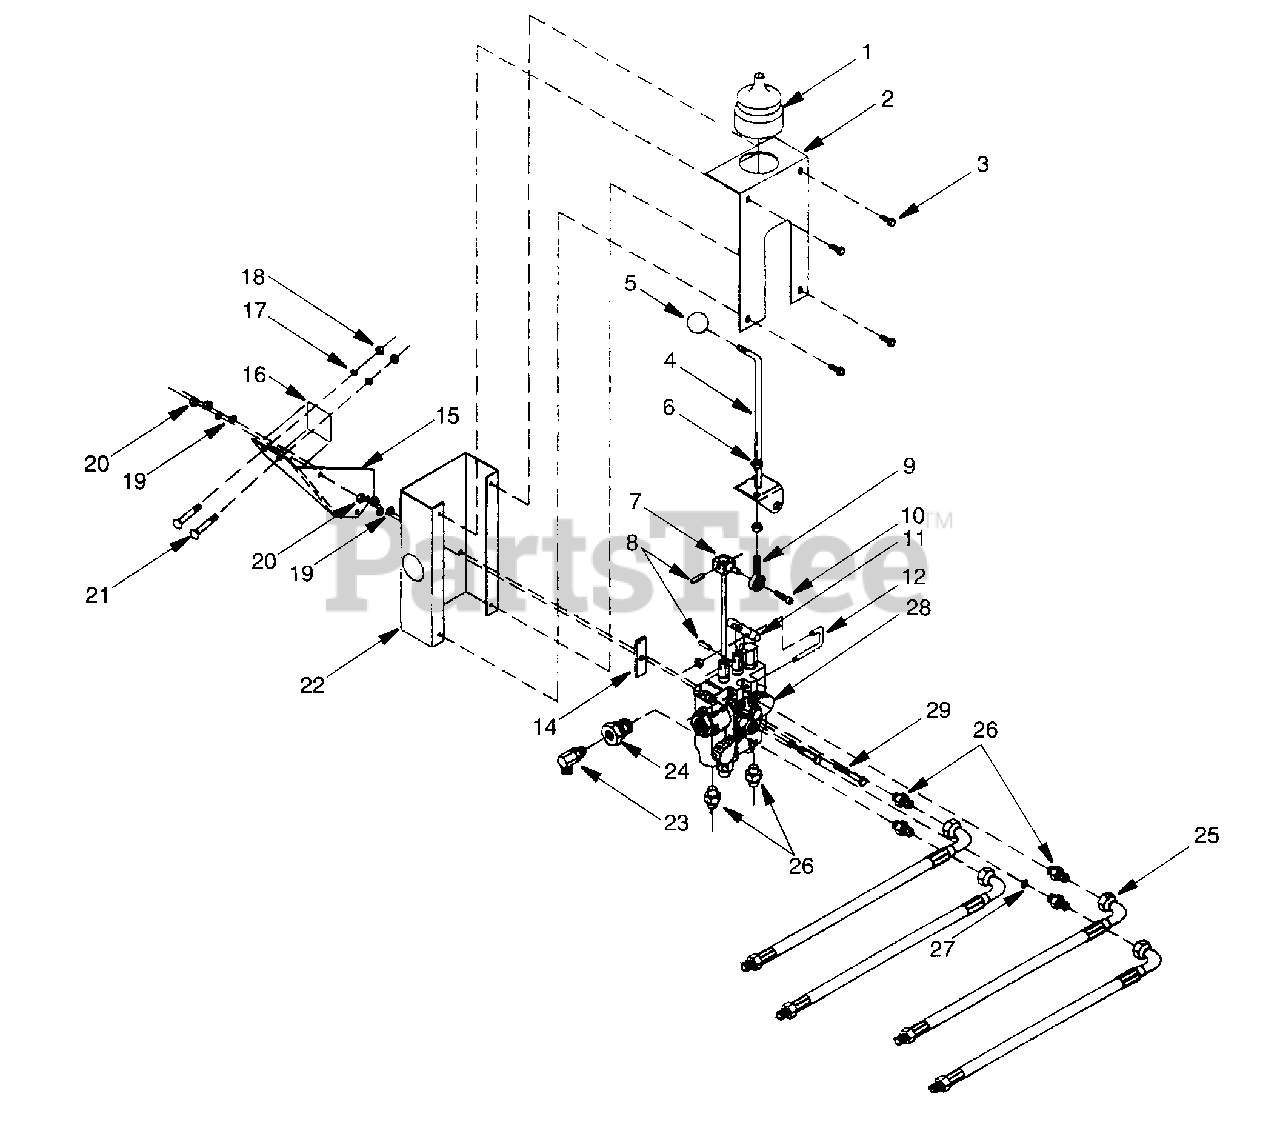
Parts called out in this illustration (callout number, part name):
1	Rubber Boot
2	End Cover
3	Self Tap Screw, 1/4 NC x 3/4
6	Hex Nut, 5/16 NF
7	Pivot Block
8	Roll Pin, 1/4 x 7/8
9	Rod End Ball Joint
10	Socket Hd Cap Screw, 1/4 x 1
12	U-Bolt
15	Valve Mounting Bracket
16	Control Valve Decal
17	Lockwasher, 3/8
18	Hex Nut, 3/8
19	Lockwasher, 1/4
20	Hex Nut, 1/4 NC
21	Carriage Bolt, 3/8 NC x 1
22	Valve Cover
23	9/16 ORM x 9/16 JICM 90°
24	Power Beyond Sleeve
25	25" Hose, 9/16 JICF x 3/4 JICM
26	Adapter, 9/16 ORM x 9/16 JICM
27	Plate Orifice, .094 Dia
28	Valve, 2 Spool Monoblock, 1800 psi
29	Cap Screw, 1/4 NC x 2.5 GR5
